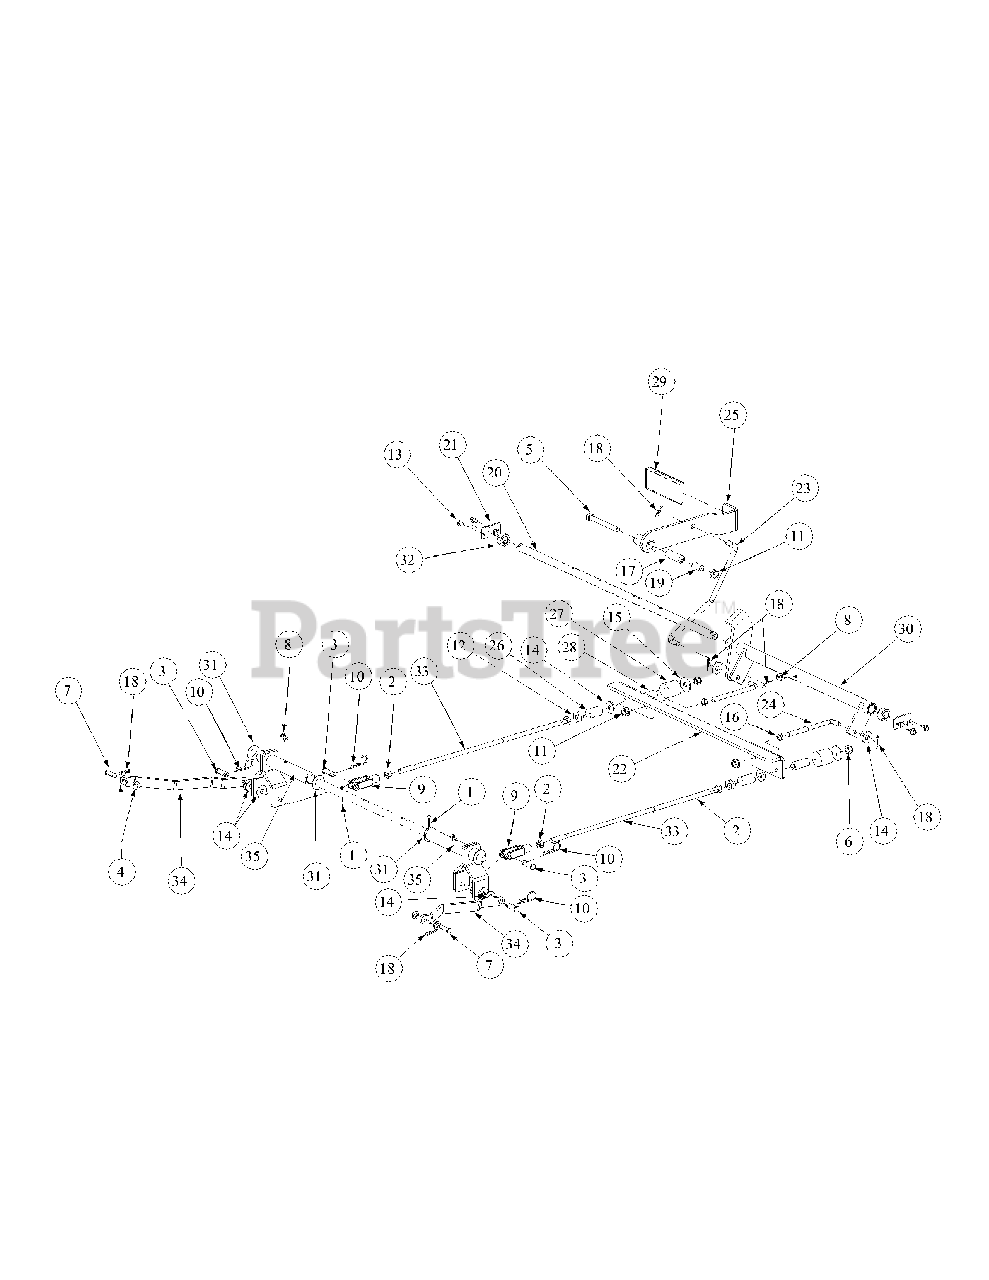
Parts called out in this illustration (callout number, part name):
1	Cotter Pin, .125 Dia x 1.0
2	Hex Nut, 3/8-16
3	Clevis Pin, 3/8 x 1-1/8
4	Flat Washer, 5/16
5	Hex Cap Screw, 3/8-16 x 3-1/2
6	Nylock Nut, 3/8-16
7	Clevis Pin, 5/16 x 1
8	Grease Fitting, 1/4 -28, 90°.
9	Yoke, 3/8-16
10	Hair Pin, 3/8" - 1/2"
11	Flange Lock Hex Nut, 3/8-16
12	Shoulder Nut
13	Screw, 1/4-20 x 1-1/2
14	Flat Washer, .406 ID x 1.0 OD x .105
15	Flat Washer, .411 x 1.25 x .100
16	Jam Nut, 3/8-16
17	Spacer, .375 x .50 x 1.75
18	Cotter Pin, .072 x 1.12 Lg
19	Spacer, .375 x .50 x 1.02 Lg
20	Bellecrank Mounting Shaft
21	Parking Brake Shaft Holder
22	Brake Bracket
23	Brake Rod
24	Connector Rod, 3/8 OD x 5.75
25	Brake Handle
26	Neutral Brake Spring
27	Force Brake Spring
28	Center Brake Hose
29	Parking Brake Grip
30	Brake Bearing Hub
31	Flat Washer, 5/8
32	Shaft Collar, .625 ID x 1" OD x .438
33	Connector Rod, 3/8 OD x 17.88 Lg
34	Rear Brake Linkage
35	Rear Brake Arm Assembly
